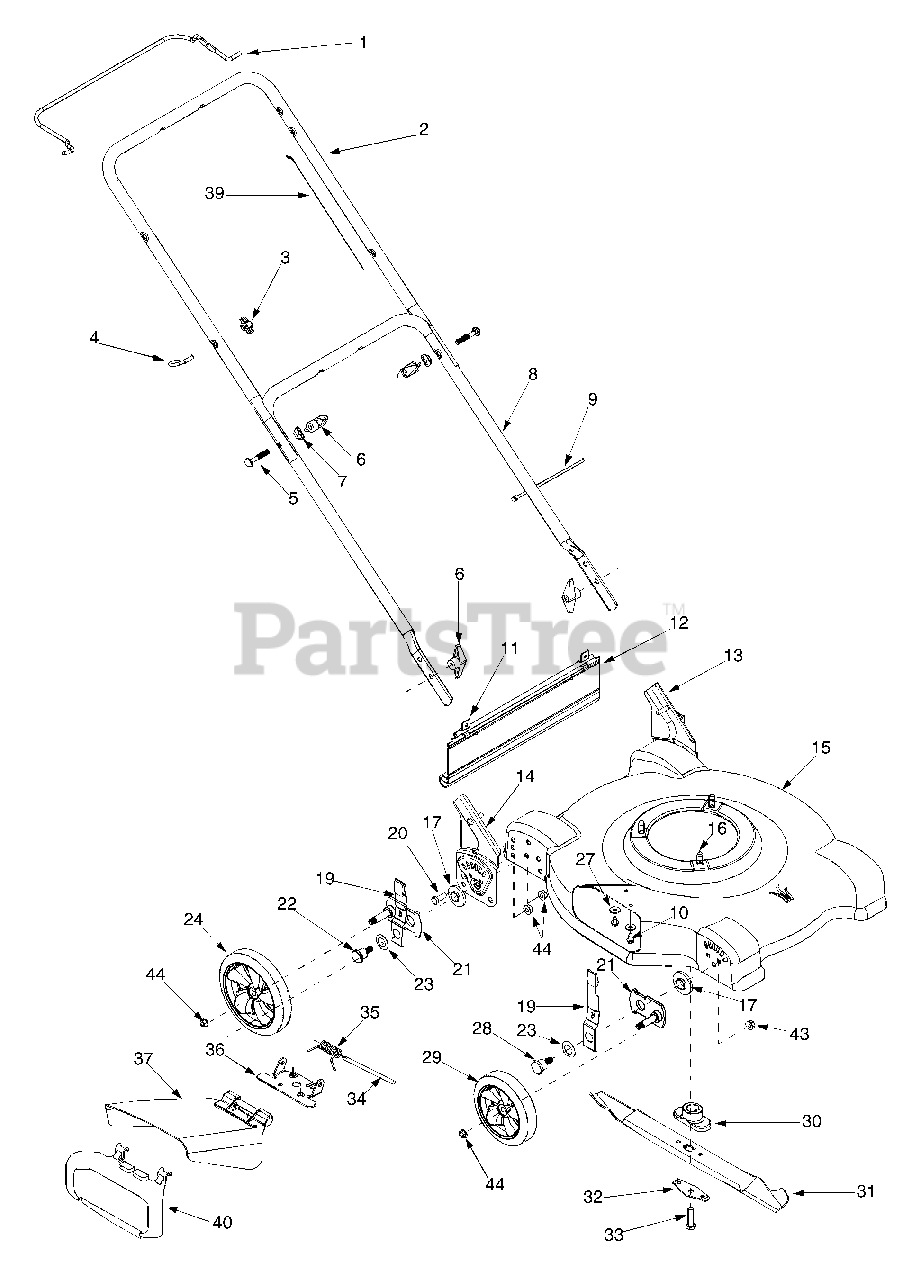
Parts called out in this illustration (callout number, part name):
3	Knob - ERS Guide 1/4-20
4	Rope Guide Bolt
5	Carriage Bolt 5/16-18 x 2.0
6	Handle Knob Assembly
7	Saddle Wash. .320 ID x .937 OD
9	Cable Tie
10	Hex Wash S-Tapp Scr 1/4-20 x .50
11	Hinge Clip
12	Trail Shield
16	Hex Wash HD Tap Scr 3/8-16 x .88
17	Height Adjuster Bearing
19	Lever Assembly
20	Hex Cap Screw 3/8-16 x .75
21	Pivot Bar
22	Shoulder Screw
23	Cupped Washer .401 ID x .870 OD
24	Wheel Ass'y 8 x 1.8 Spoke Bar Grey
27	Cup. Wash. .265 ID x .75 OD x .062
28	Shoulder Screw 3/8-16
29	Wheel Assembly Complete 7 x 1.8
30	Blade Adapter
31	Blade 22"
31	Mulching Blade 22"
32	Blade Bell Support
33	Hex Screw 3/8-24 x 1.5" Lg. (Gr. 8)
34	Hinge Pin
35	Torsion Spring
36	Chute Hinge
37	Chute Deflector
37	Side Dis. Chute Ass'y
39	Control Cable 37.25" Lg.
39	Blade Control Cable 40"
39	Control Cable 48.25" Lg.
40	Mulch Plug
44	Flanged Lock Nut
45	Shroud
